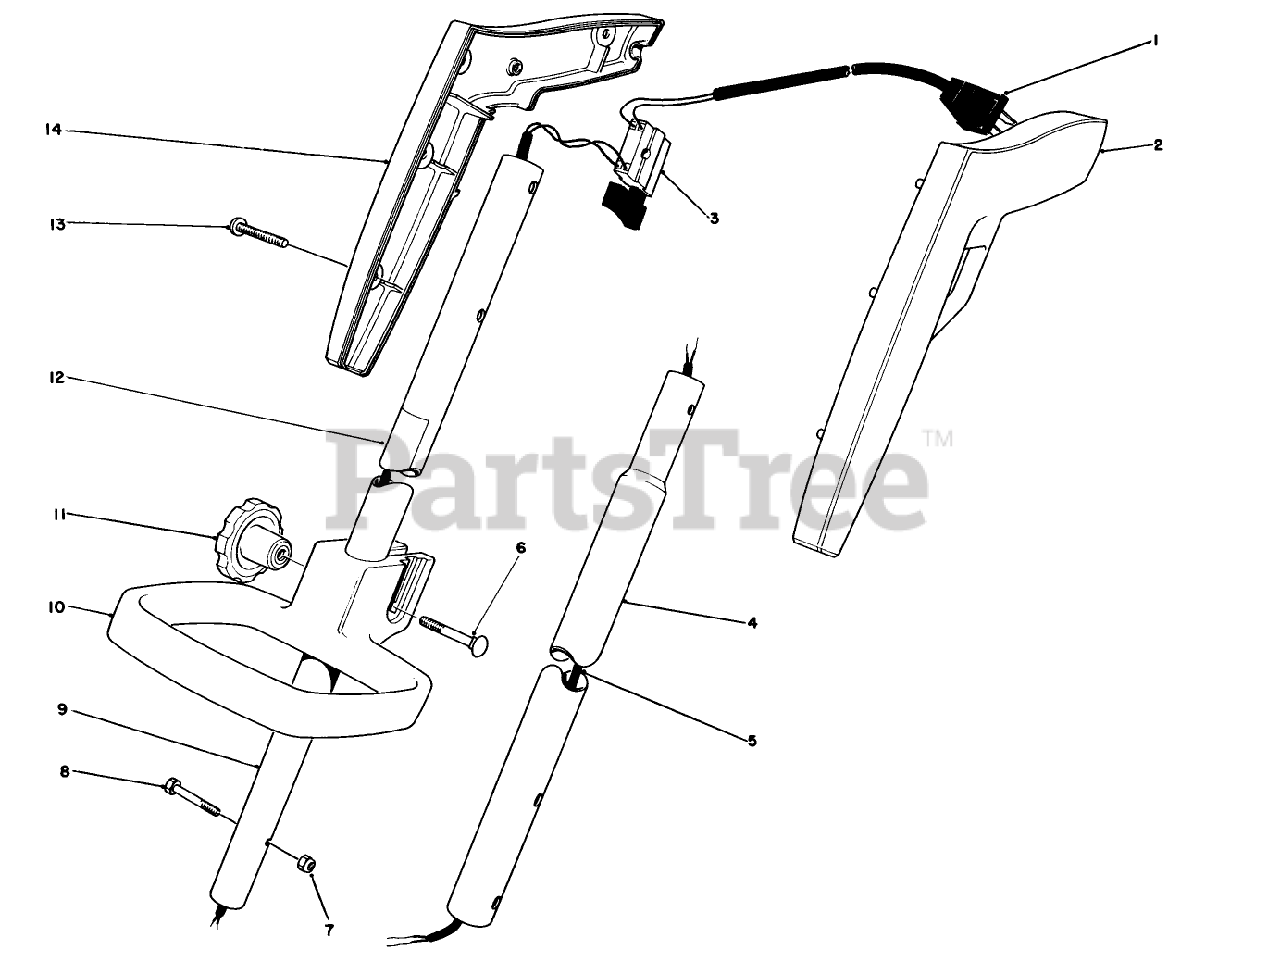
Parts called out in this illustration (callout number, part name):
3	SWITCH SINGLE SPEED
6	BOLT-CARR
7	NUT-LOCK, NI
